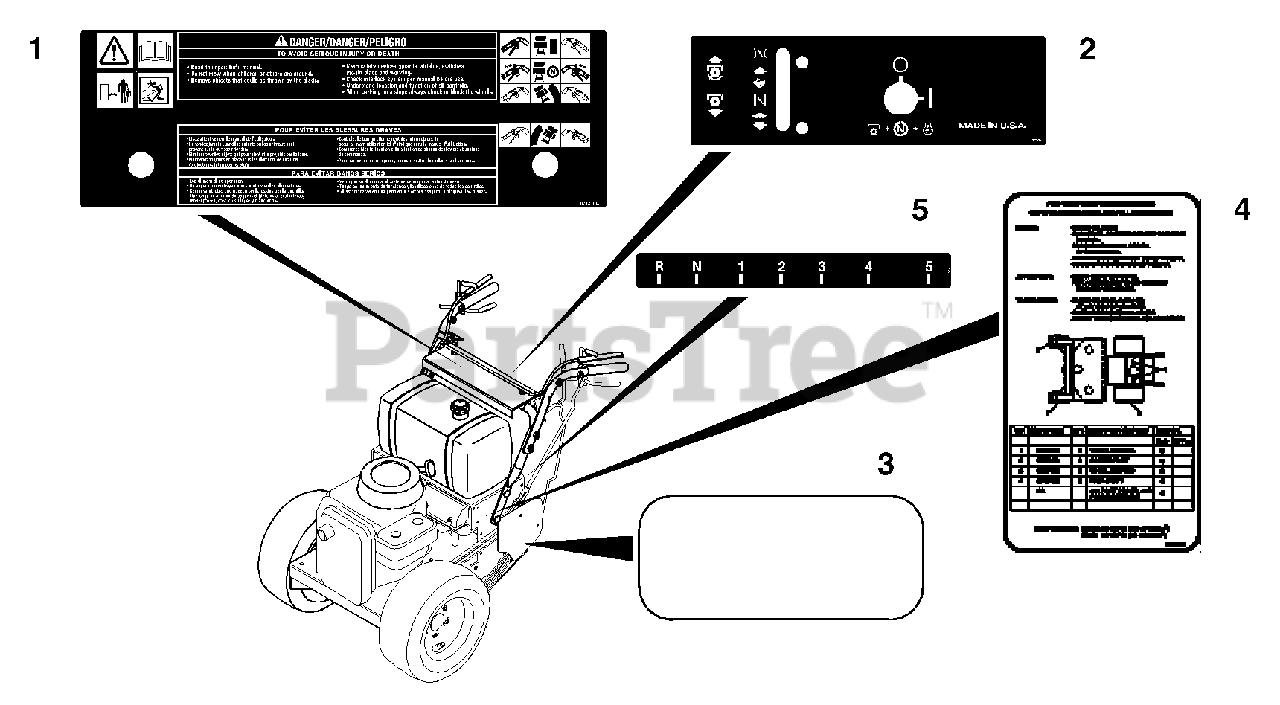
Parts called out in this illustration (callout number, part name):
1	Decal-Pro-150 Safety
2	Decal-Control Panel
2	Decal, Control Panel
3	Decal, Pro-150 12.5HP
3	Decal-Logo
3	Decal, Logo
4	Decal-Pro 150 Maintenance
5	Decal-Shifter
